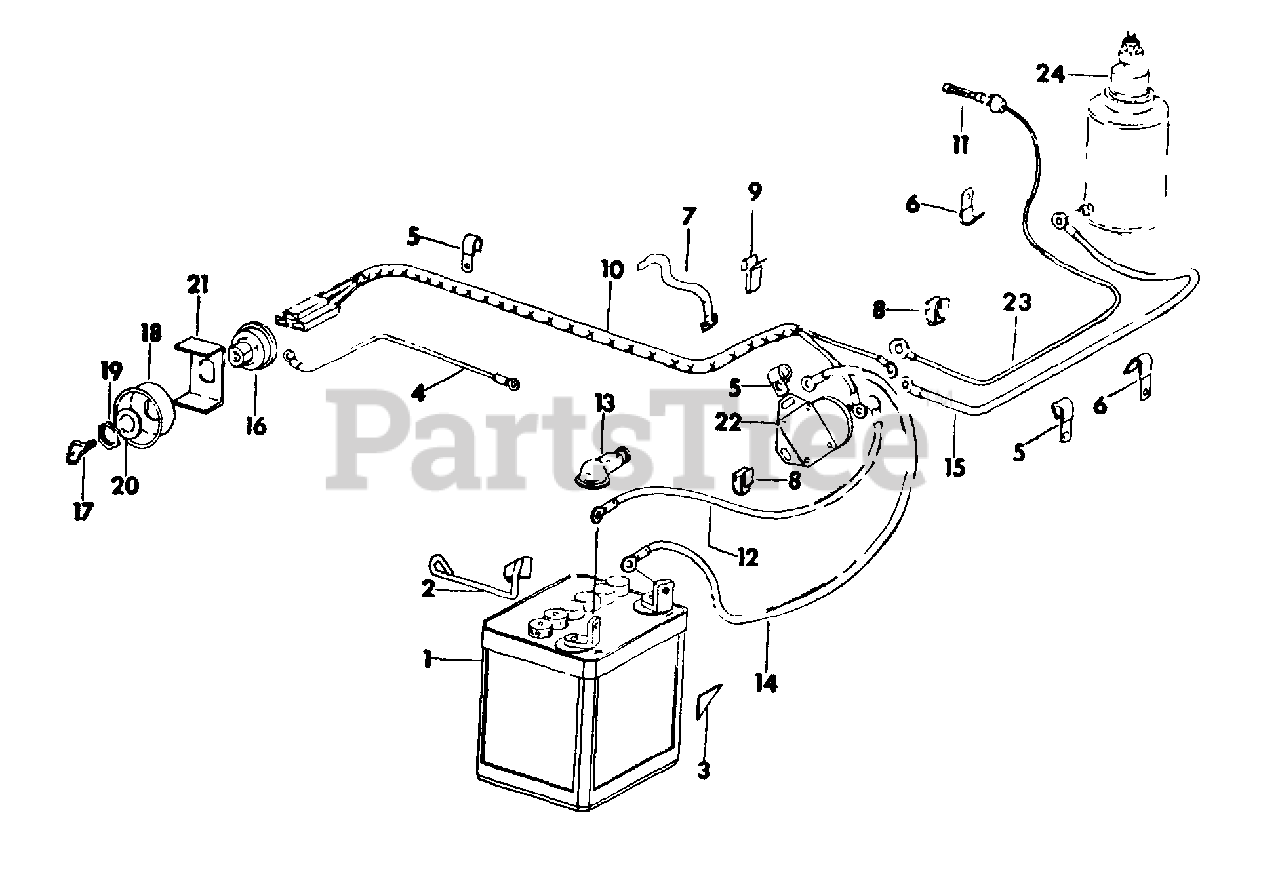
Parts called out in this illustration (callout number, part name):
1	BATTERY, LOW-MAINTENANCE -12 VOLT-
2	CLAMP ASSY, BATTERY
3	PAD, BATTERY
4	CABLE ASSY, SWITCH TO GROUND
6	CLIP, CABLE
9	CLIP, CABLE SPEED
10	HARNESS, CABLE
11	FUSE, 32 VOLT, 7-1/2 AMP
12	CABLE, BATTERY POSITIVE
13	COVER, BATTERY TERMINAL
14	CABLE, BATTERY GROUND
15	CABLE, SWITCH TO STARTER
16	SWITCH, MAGNETO IGNITION AND STARTING
17	KEY, IGNITION SWITCH
18	SOCKET, IGNITION SWITCH
19	NUT, MAGNETO IGNITION KEY MOUNTING
20	WASHER, MAGNETO IGNITION KEY MOUNTING
21	RETAINER, IGNITION SWITCH
22	SWITCH, MAGNETIC
23	CABLE, SWITCH TO FUSE
24	STARTING MOTOR
